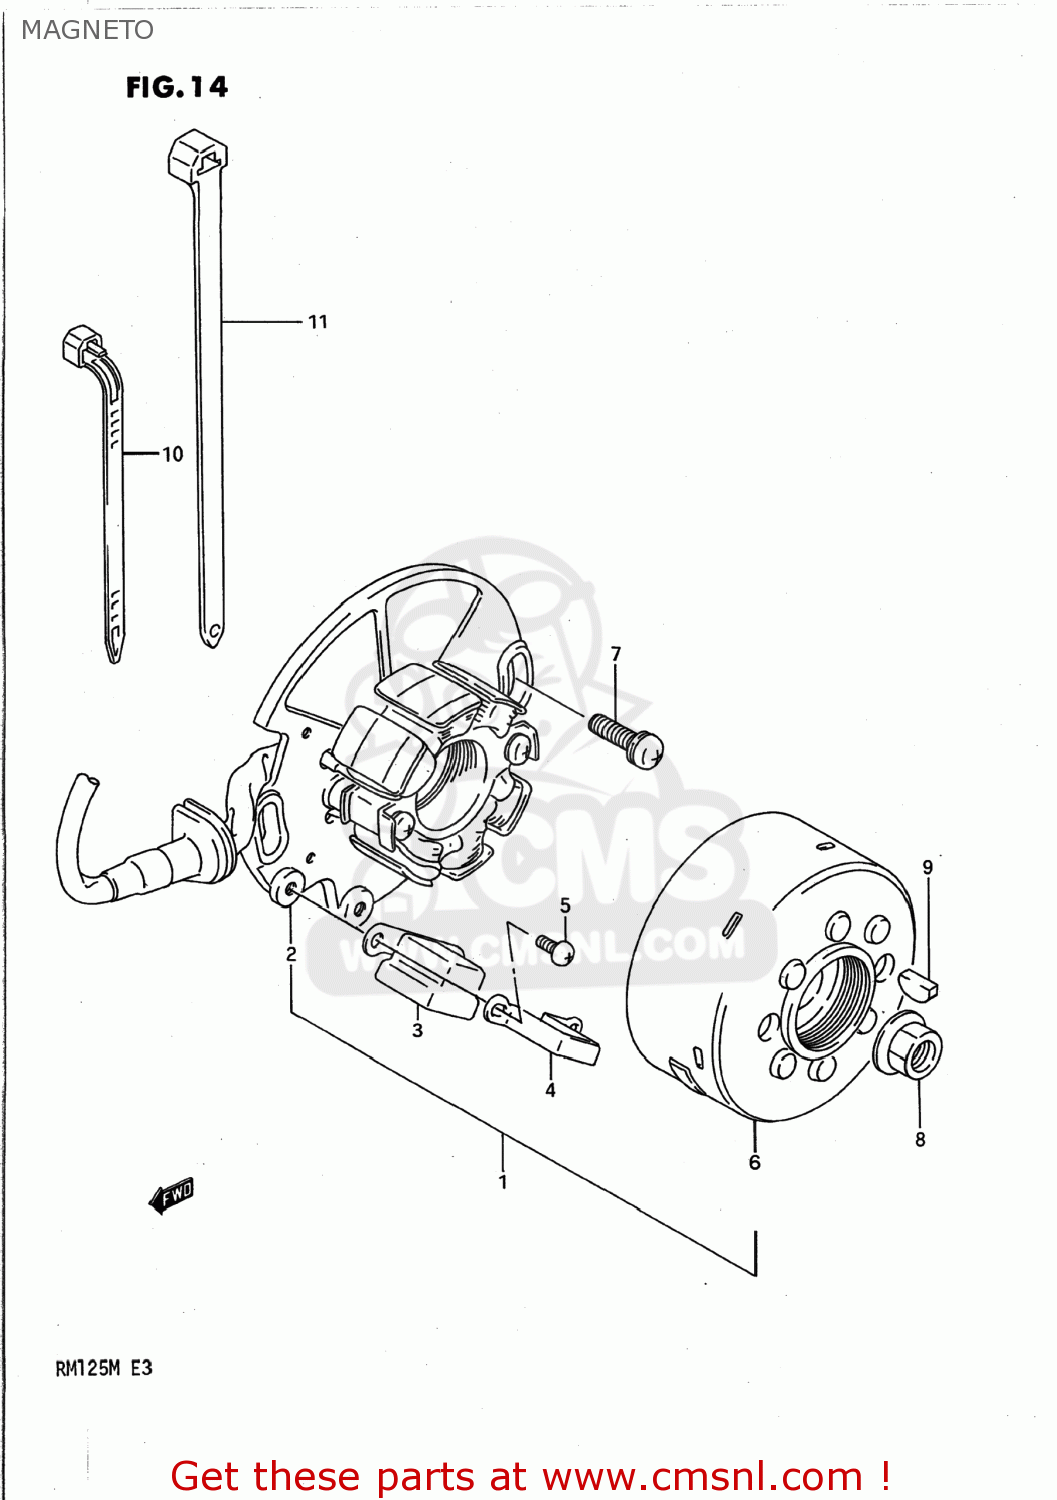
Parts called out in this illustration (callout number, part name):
1	MAGNETO ASSEMBLY
2	STATOR ASSEMBLY
3	COIL ASSEMBLY,PICK-UP
4	HOLDER,PICK UP COIL
5	SCREW
6	ROTOR
7	SCREW
8	NUT
9	KEY 4MM
10	CLAMP(L:125)
11	CLAMP
